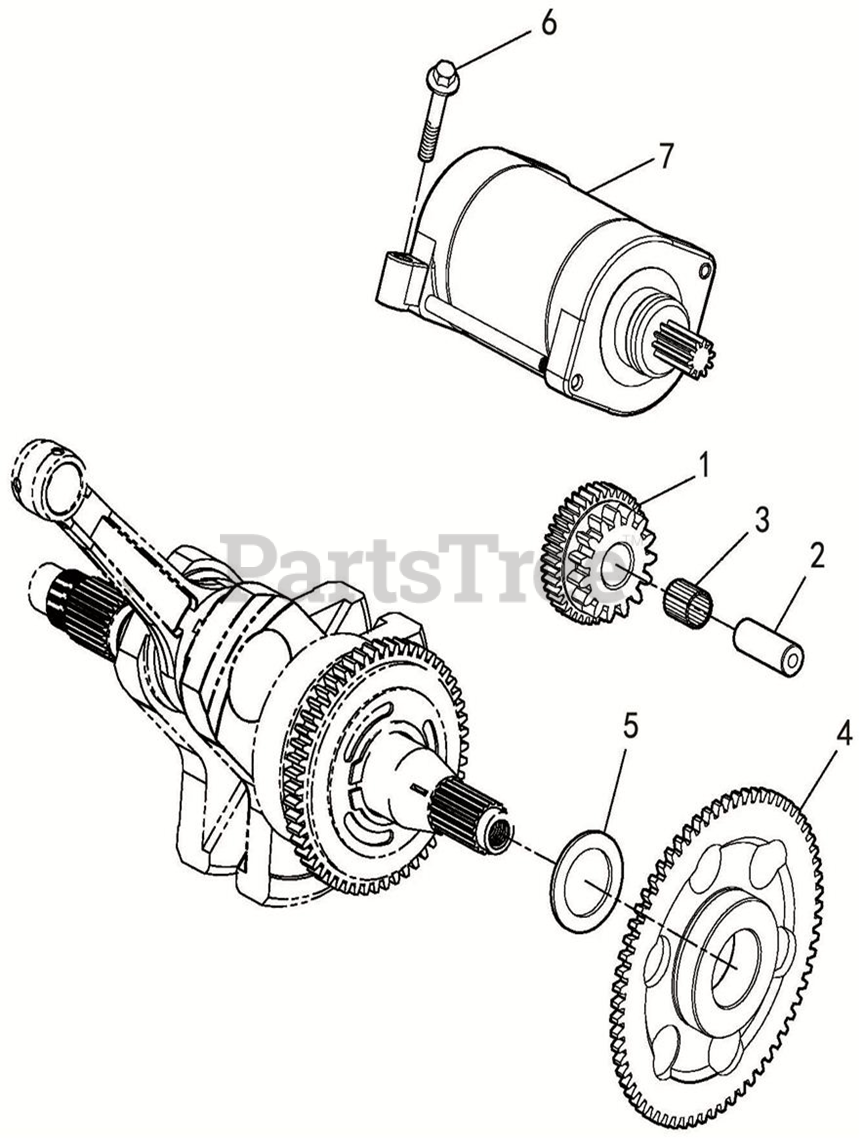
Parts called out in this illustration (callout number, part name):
1	DUPLICATE GEAR
2	DUPLICATE GEAR SHAFT
3	NEEDLE BEARING
4	STARTER GEAR
5	WASHER 25x39x1
6	HEX FLANGE BOLTS M6X30
7	STARTER MOTOR
